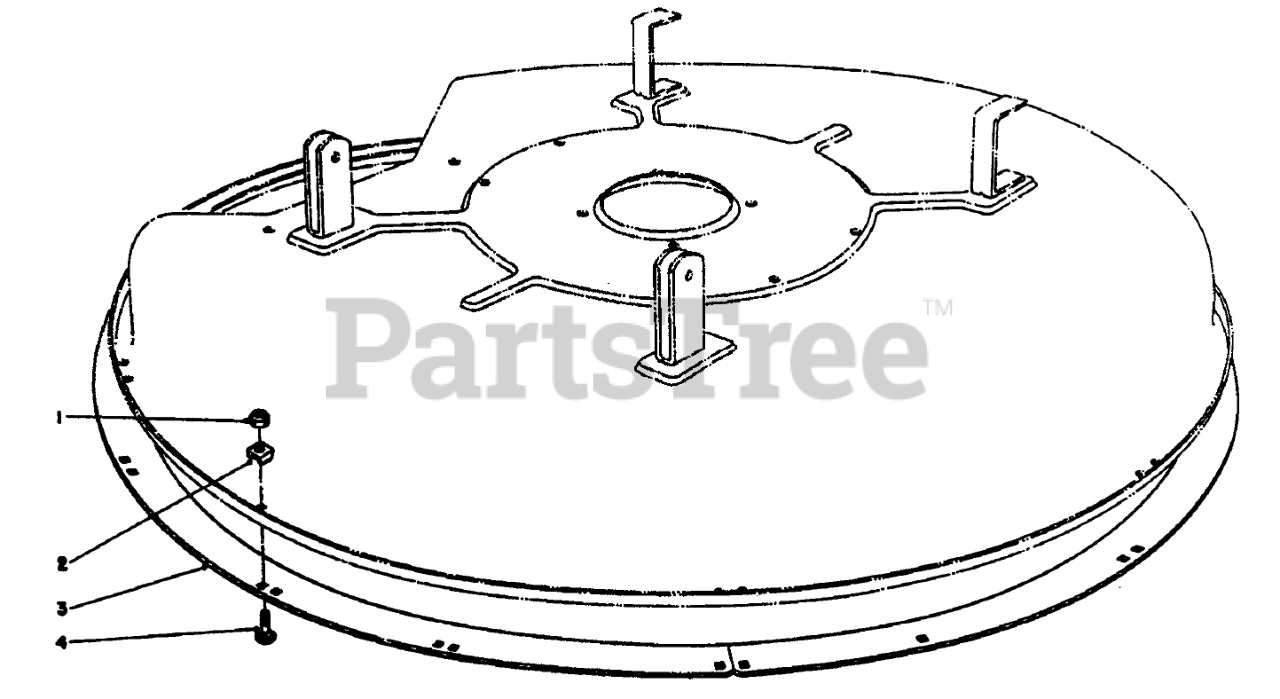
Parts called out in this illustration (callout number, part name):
1	NUT-LOCK, NI
2	DECK RING SPACER
3	DECK RING B
4	BOLT-CARR
